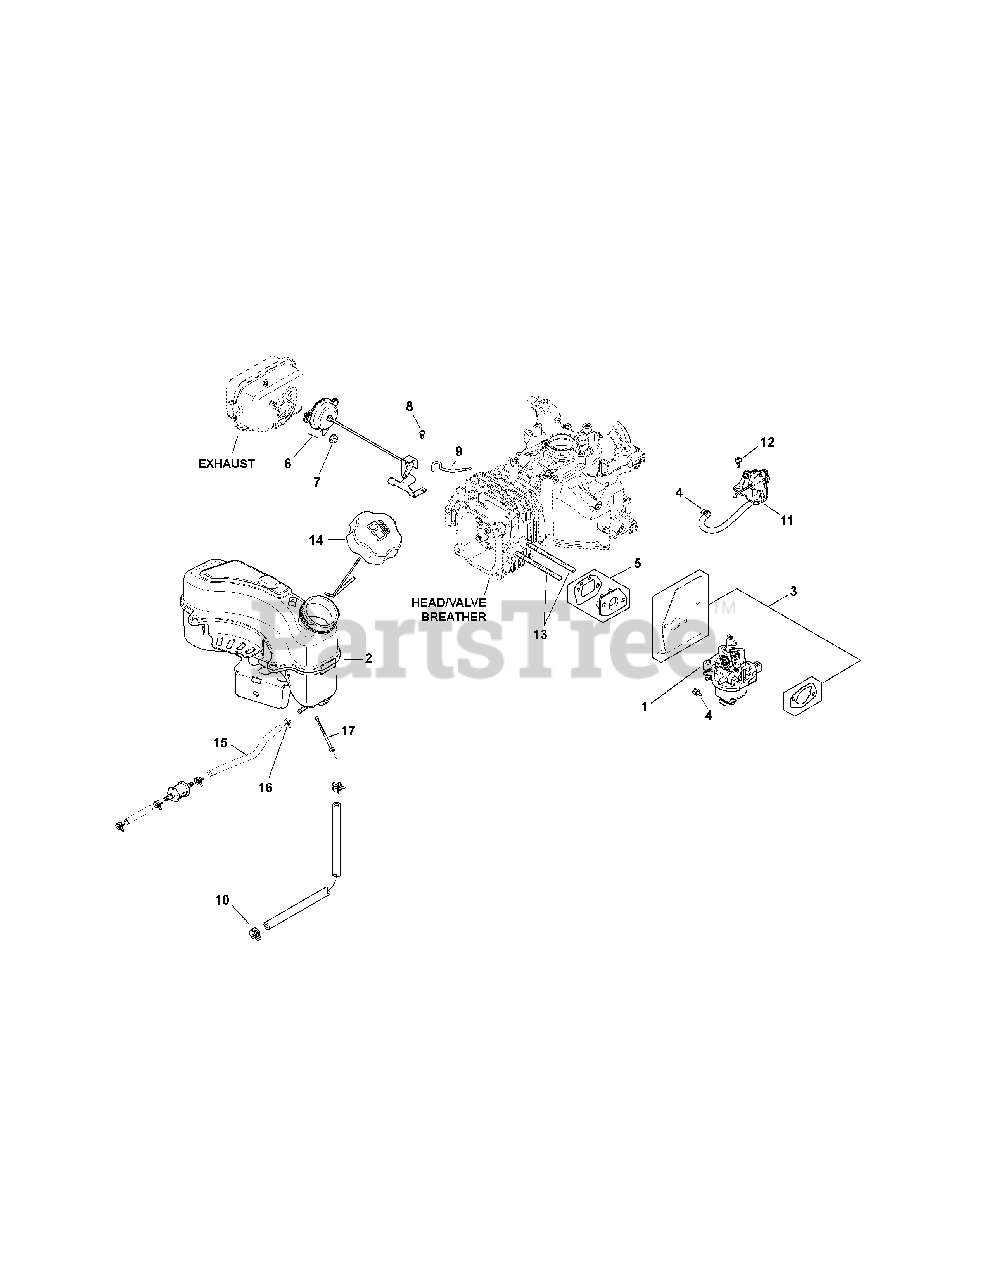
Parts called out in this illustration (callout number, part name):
1	Carburetor, 13MM Auto Choke
2	Fuel Tank Assembly
3	Kit, Gasket
5	Carburetor Spacer Kit
6	Arm, Assembly
7	Nut, Hex Flange, M6
8	Screw, M4 Thread Forming
9	Linkage, Auto Choke
11	Diaphragm, Assembly
12	Screw, Shoulder
13	Stud, M6 x 1.0 x 93
14	Fuel Cap Assembly
15	Fuel Hose, Low-Permeation
17	Filter, Fuel In-Nipple
